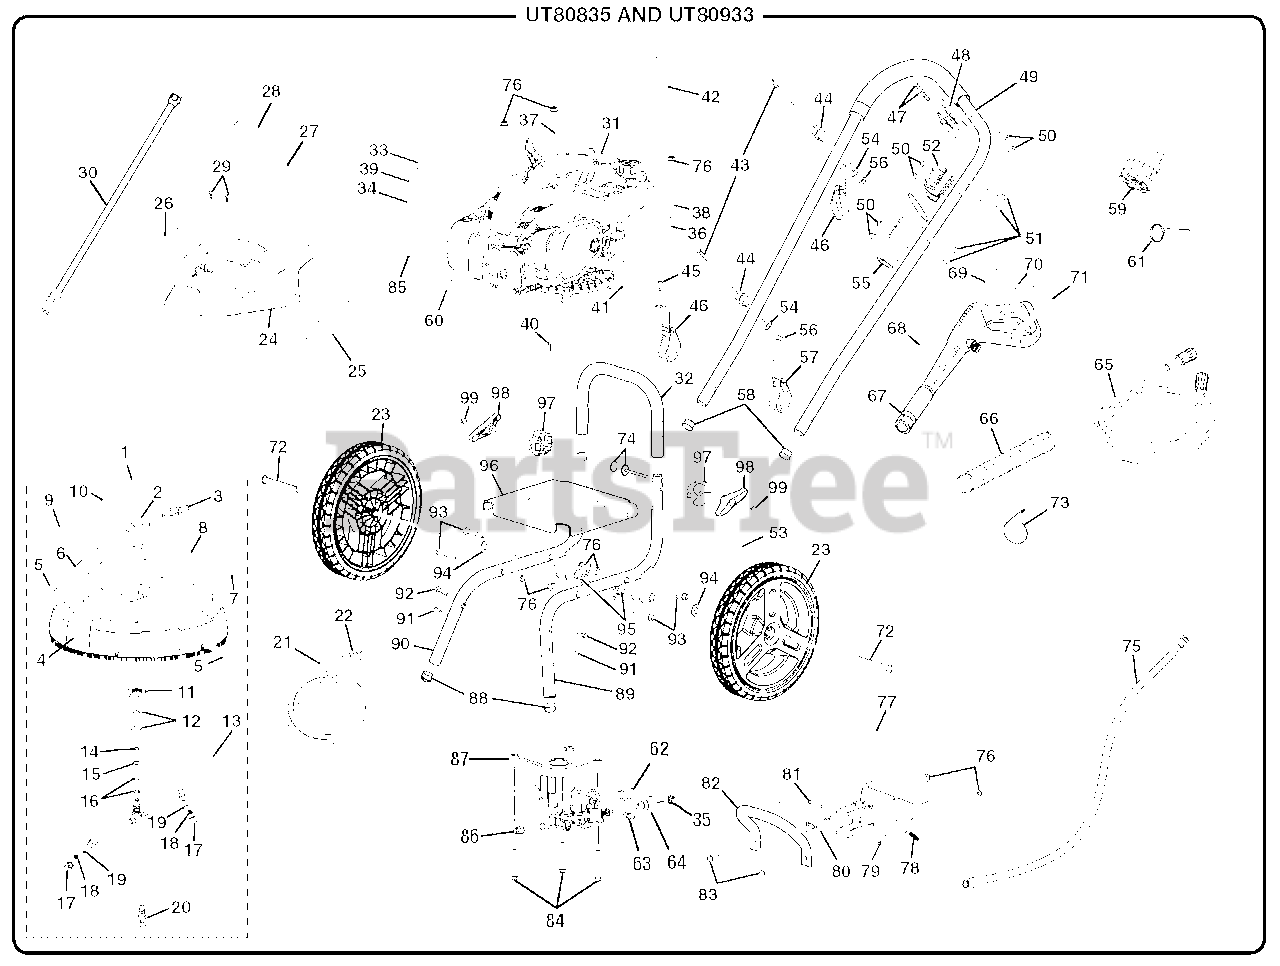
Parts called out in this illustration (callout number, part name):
1	Deck Assembly
2	Deck Pivot Assembly
3	1/8 Quick Connect (BSPP)
4	Deck w/Brush Assembly
5	No Hands/Feet Label
6	Surface Cleaner Label
7	Deck Danger Label (FR)
8	Deck Pressure Washer Label
9	Deck Logo Label
10	Deck Danger Label
11	Nut (M22)
12	Washer (D12.2 x D22 x .8t)
13	Deck Swivel w/Nozzle Assembly
14	O-Ring (4.5 x 1.8)
15	Washer (D17.9 x D13.7 x 1.5t)
16	Washer (D17.9 x D11.1 x 2.9t)
17	Nozzle Nut
18	Nozzle w/015 Jet (1/8 NPT)
19	O-Ring (4.5 x 1.8)
21	Injection Hose
23	Wheel (12 in. x 2 in.)
24	Front Shroud Assembly
25	Shroud Warning Label (FR)
26	Shroud Warning Label
27	PSI/GPM Performance Label (ENG/FR)
28	Deck Removal Label
29	Screw (12-24)
30	Wand Assembly
31	Subaru 190cc Engine
32	Frame Connector Assembly
33	Hot Muffler Label
34	EMC Label
35	Filter Screen
36	Performance Label
37	Inquires Label
38	E85 Label
39	Combustion Warning Label
40	Output Shaft Key
41	Quick Start Label
42	Danger Hang Tag Label
43	Bolt (M5 x 40 mm)
44	Spring Clip
45	Screw (12-14 x 1/2 in., Pan Hd.)
46	Hose Storage Strap
47	Screw (1/4-20 x 40 mm, Hex Hd.)
48	Trigger Handle Lock
49	Upper Handle Assembly
50	Lock Nut (1/4-20)
51	Screw (1/4-20 x 45 mm, Truss Hd.)
52	Upper Trigger Handle Holder
53	Data Label
54	Washer (D15 x D5.5 x 2t)
55	Lower Trigger Handle Holder
56	Lock Nut (M5)
57	Hose Attachment System Strap
58	End Cap (25 mm)
59	6-N-1 Nozzle Assembly
60	Release Pressure Label
61	Nozzle Cleaning Tool
62	Outlet Tube
63	Detergent Suction Kit
64	Inlet Tube
65	Hose
66	Tube Conduit
67	Trigger Handle Assembly
68	Logo Label (Homelite Trigger Handle)
69	Warning Label (ENG)
70	Warning Label (FR/SP)
71	Maximum Pressure Label
72	Axle (D13.3 x 95 mm)
74	Carriage Bolt (1/4-20 x 88.5 mm)
75	Deck High Pressure Hose Assembly
76	Lock Nut (M8 x 1-1/4 mm)
77	Deck Bracket Assembly
78	Deck Lock Spring
79	Hitch Pin
80	Release Handle
81	Connect Pin
82	Lift Handle
83	Hex Bolt (M8 x 20 mm)
84	Hex Bolt (M8 x 60 mm)
85	Logo Label (Subaru)
86	Thermal Release Valve
87	Pump (Himore)
88	Frame Glide
89	Left Frame Assembly
90	Right Frame Assembly
91	Screw (T-30 Torx, 1/4-20, Truss Hd. Shoulder)
92	Screw (1/4-20 x 40 mm, T-30 Torx Flat Hd.)
93	Hex Bolt (M8 x 50 mm, Flange Hd.)
94	Washer (1/2 in.)
95	Hitch Pin
96	Engine Plate
97	Handle Spacer
98	Knob Assembly
99	Acorn Nut (Center lock)
